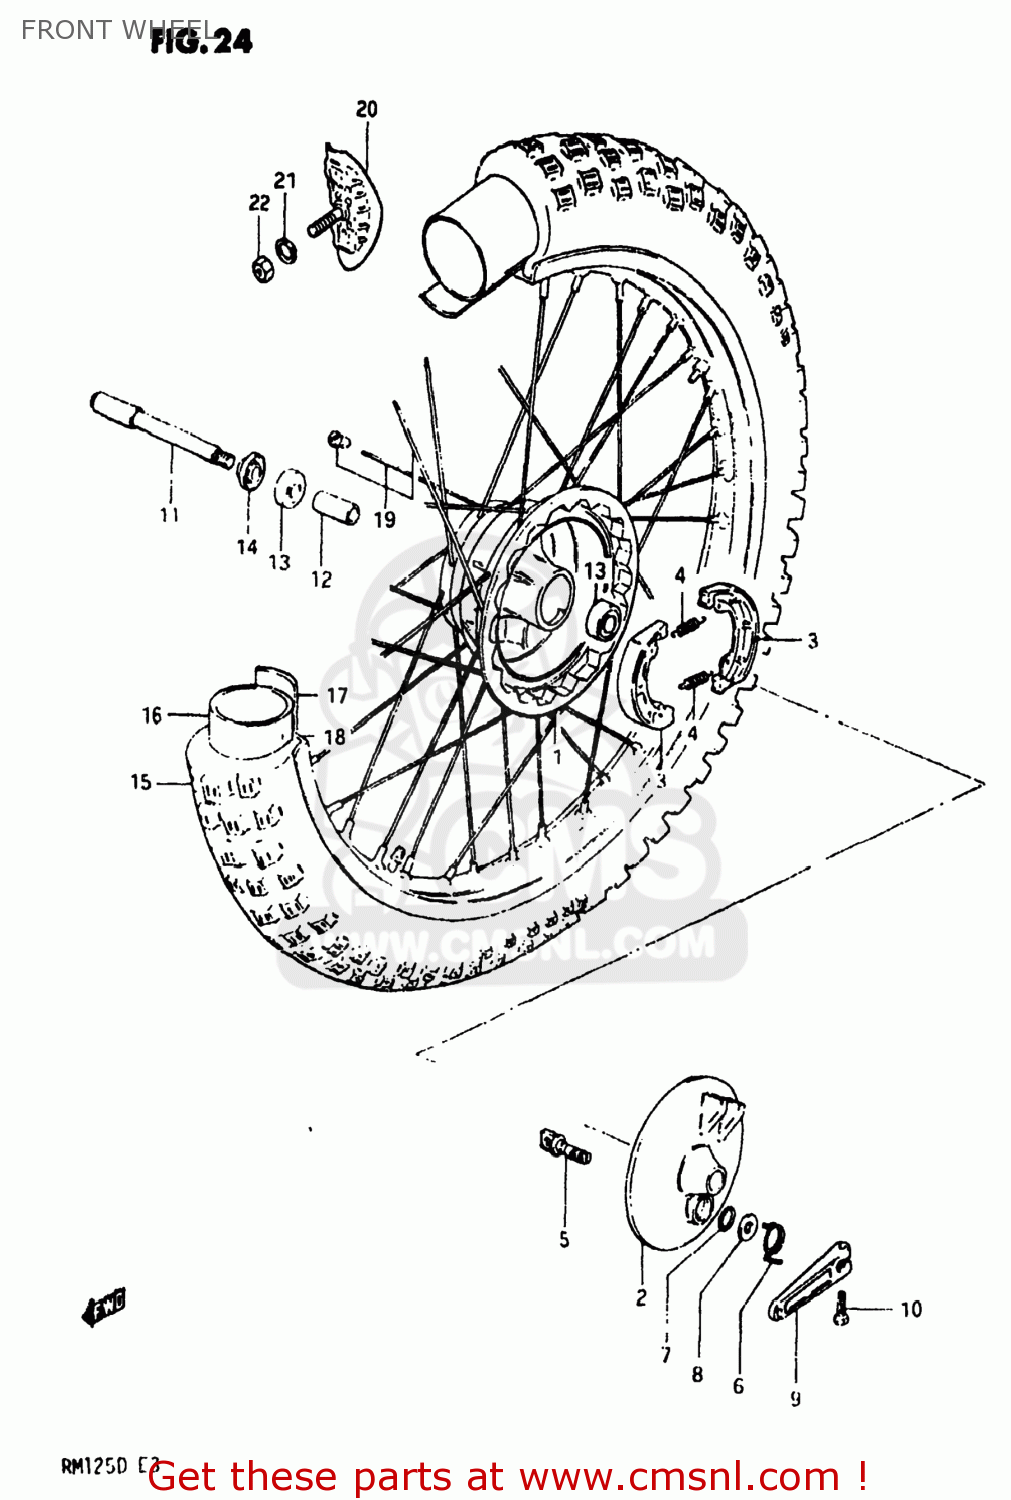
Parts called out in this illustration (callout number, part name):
1	HUB,FRONT
2	PANEL,FRONT HUB
3	SHOE,BRAKE
4	SPRING
5	CAM,FR BRAKE
6	SPRING
7	O RING(D:2.5,ID:11.4)
8	WASHER(12.5X20X1)
9	LEVER,FRONT BRAKE CAM
10	BOLT
11	AXLE,FRONT
12	SPACER,FRONT HUB BEARING
13	BEARING
14	SPACER,FRONT AXLE,RIGHT
15	TIRE,FRONT
16	TUBE
17	PROTECTOR,WHEEL,INNER
18	RIM,FRONT WHEEL
19	SPOKE SET,FRONT
20	STOPPER,BEAD
21	WASHER
22	NUT 8MM
